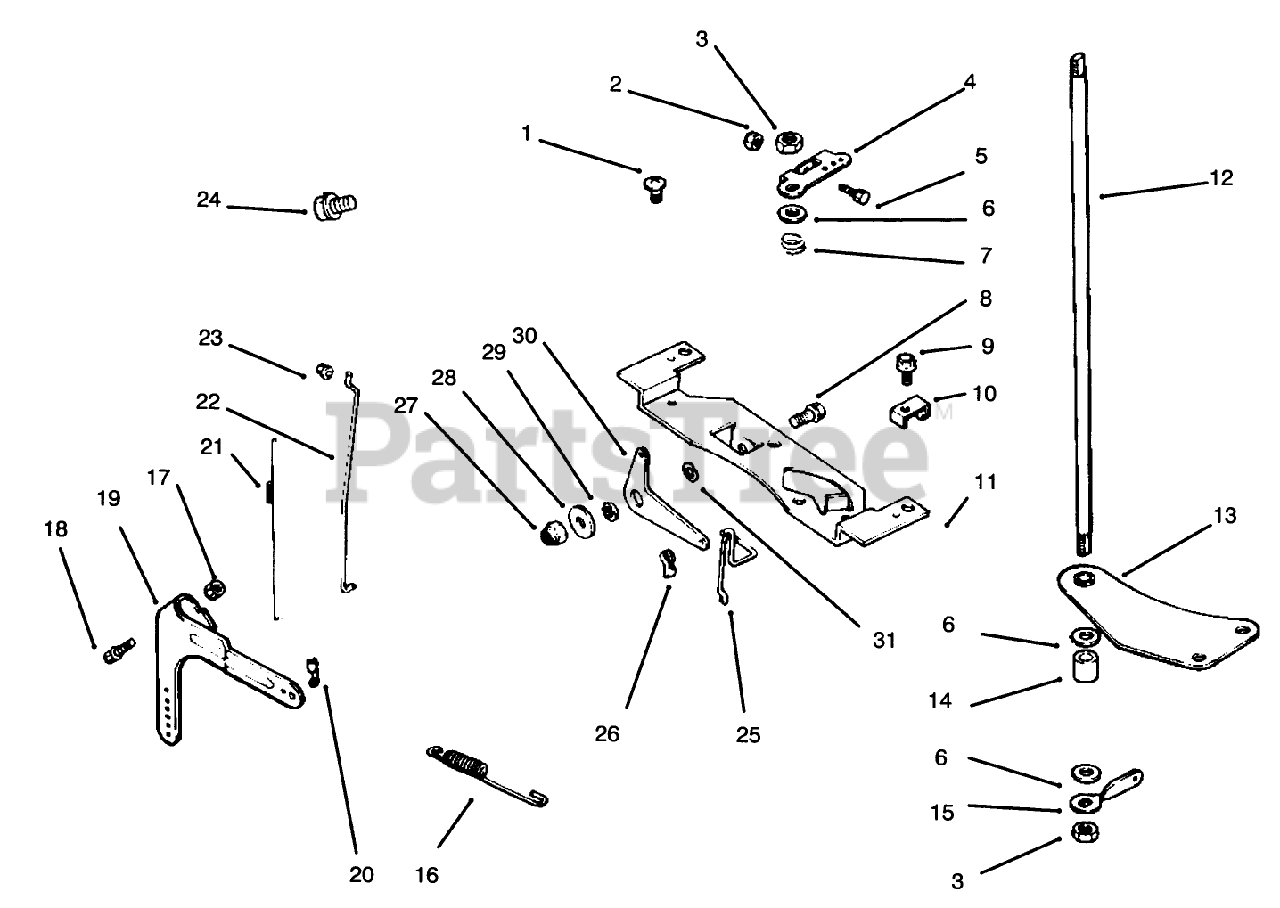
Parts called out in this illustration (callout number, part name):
4	Lever-Throttle Control
5	Screw-HHF M4x0.7x28 (Only On: 72042, 72063, 72062, 72043)
6	Washer
7	Spring-Throttle Shaft
11	Bracket-Control
12	Shaft-Throttle
13	Bracket-Throttle Shaft
15	Lever-Throttle Control
16	Spring-Governor
19	Lever-Governor
20	Bushing-Linkage
21	Spring-Linkage
22	Linkage-Throttle (Only On: 72103)
23	Bushing
25	Linkage-Choke
26	Bushing-Linkage
28	Washer
30	Lever-Choke
31	Washer
